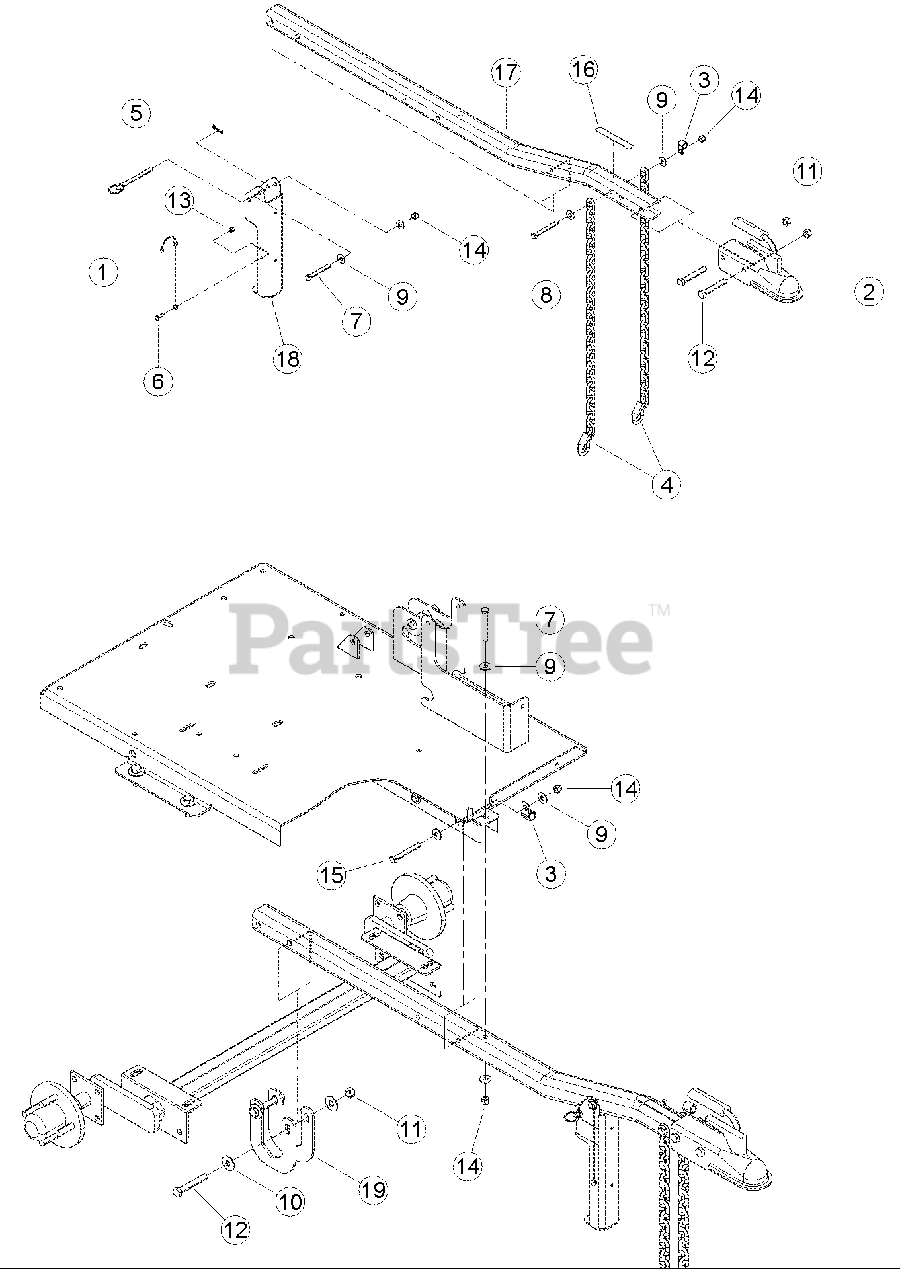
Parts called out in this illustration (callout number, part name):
1	LANYARD, NYLON
2	COUPLER, 50 MM BALL
3	CLAMP, 9/16 COATED
5	PIN, 3/8 HITCH
6	BOLT, 1/4 X 3/4 HEX HD GR5 ZP
7	BOLT, 3/8 X 3 HEX HD GR5 ZP
8	BOLT, 3/8 X 3-1/2 HEX HD GR5 ZP
9	WASHER, 3/8 FLAT ZP
10	WASHER, 1/2 FLAT ZP
11	NUT, 1/2 CENTERLOCK GRB ZP
12	BOLT, 1/2 X 3-1/4 HCS GR5 ZP
13	NUT, 1/4 NE NYLOCK ZP
14	NUT, 3/8 NE NYLOCK ZP
15	BOLT, 3/8 X 3-1/4 HEX HD GR5 ZP
16	DECAL, HITCH LOAD
17	POLE, C/S HITCH
18	STAND, JACK
19	PLATE, HITCH
